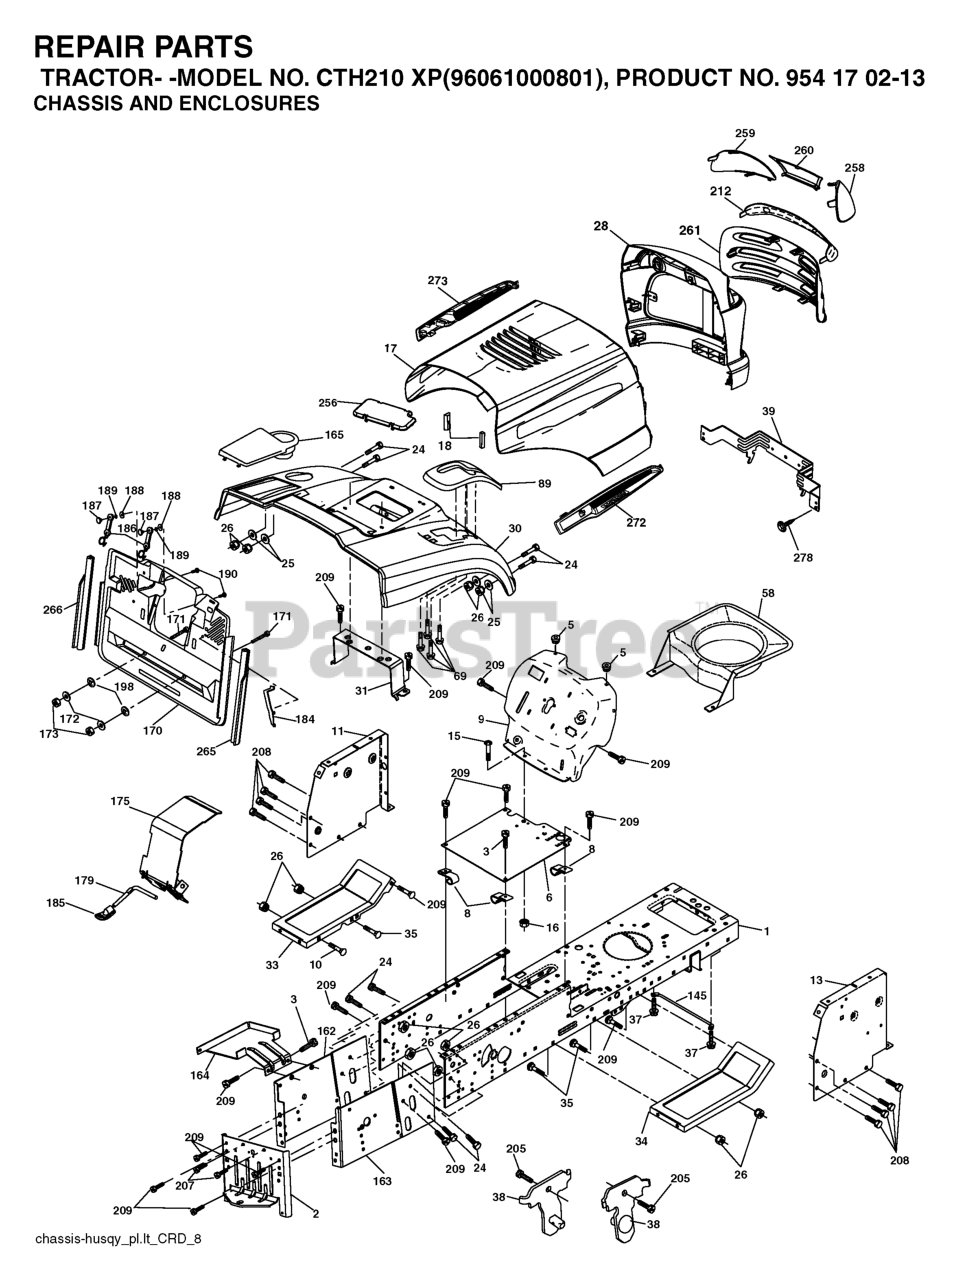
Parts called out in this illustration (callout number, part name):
2	DRAWBAR
3	SCREW 3/8-16X3/4
5	BUMPER.RUBBER.HOOD
6	PLATE
8	CLIP,INSULATOR
9	DASH.SLKSCR.STL.PLM
10	BOLT D
11	PANEL.DASH.LH.LTX
13	PANEL ASM, DASH RH
15	Screw, Machine, Truss Head 5/16-18 UNC x 3/4
16	NUT
17	VENT.HOOD.LASER.III
18	BUMPER.HOOD.LARGE.1.75"
25	WASHER
26	NUT
30	CONSOLE.CRD.AUTO.GRY
31	BRACKET SUPPORT FENDER
33	FOOTREST PNT LH
34	FOOTREST PNT RH
37	Screw 5/16-18 x 1/2 Hex, Self Tapping 5/16-18 x 1/2
38	BRACKET ASM PIVOT MOWER REAR
39	BRACKET PIVOT LASER
69	SCREW.HI-LO.CONSOLE
89	CONSOLE.CRD.AUTO.GREY.2005
145	ROD PIVOT CHASSIS/HOOD
162	BRACKET
163	BRACKET EXTEN CHASSIS RH CRD
165	RP.COVER.BATTERY.CRD.GREY
172	WASHER
175	DOOR TRAP
179	ROD PIVOT FBI
184	BRACKET.ACTUATOR.BAGGER.SRD
186	LATCH ASSY
187	WELDNUT
189	LOCKWASHER #10
190	SCREW
207	SCREW, 5/16-18 X 1/2
208	SCREW 3/8-16X1/2
209	SCREW, 3/8-16X3/4
212	INSERT.LENS.REFLECTIVE
256	COVER FENDER CRD
258	LENS LH
259	LENS LH
260	COVER.LENS.HUSQ.LASER
265	SEALING
266	SEALING
272	VENT.HOOD.LASER.
273	VENT.HOOD.LASER.
278	SCREW
